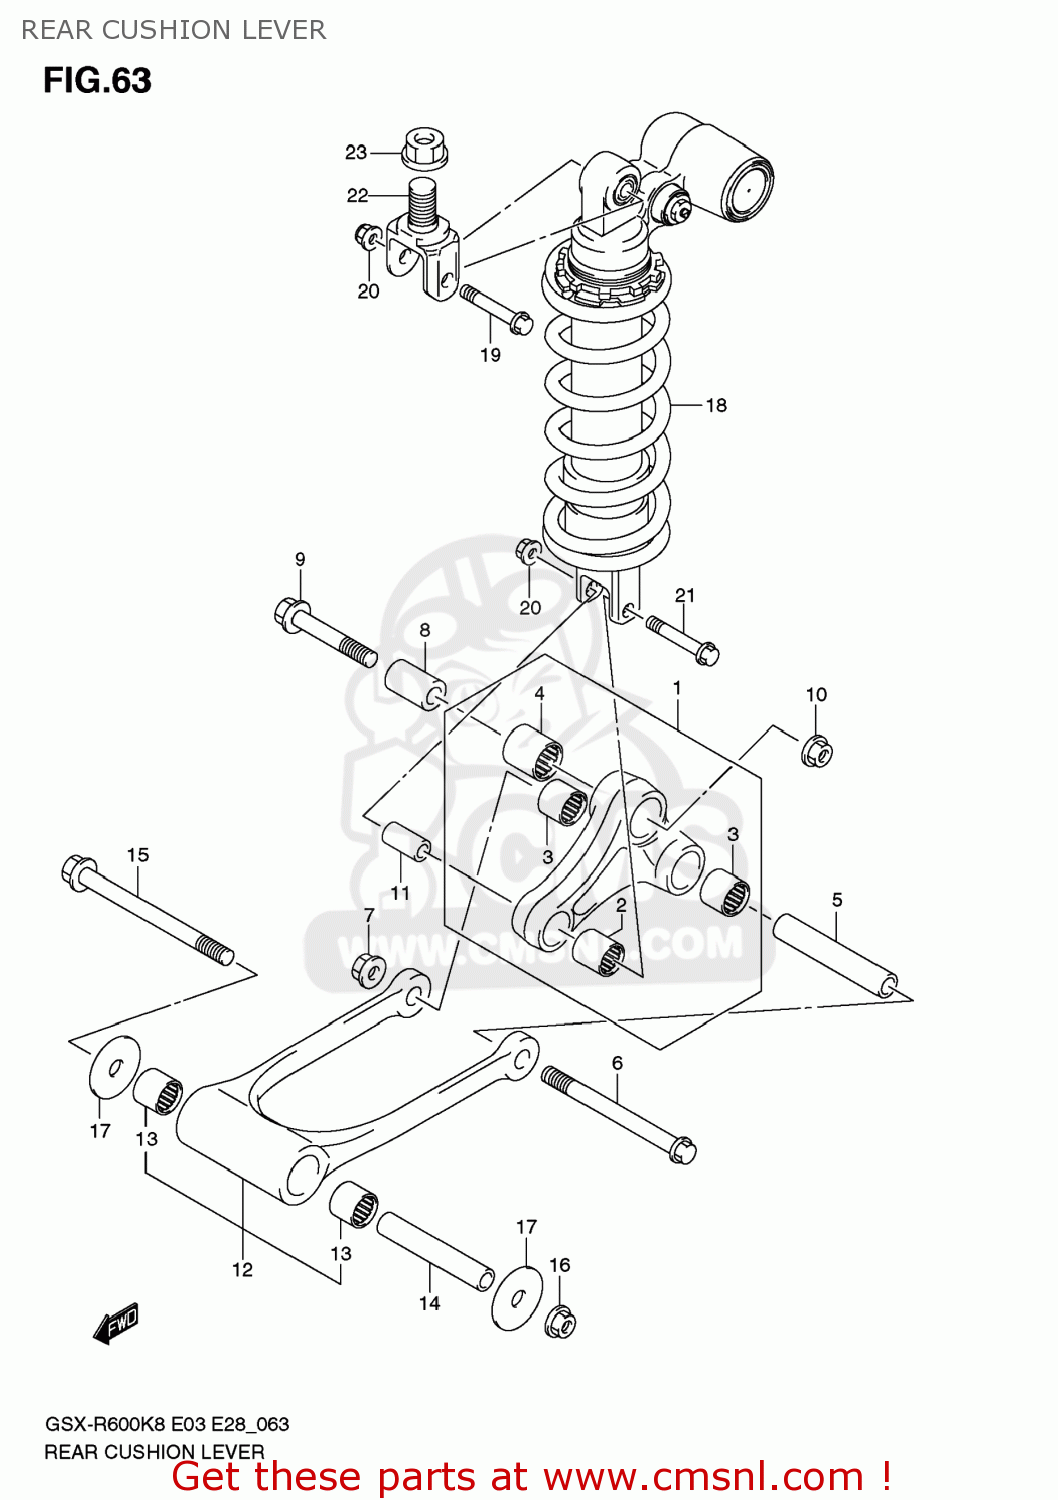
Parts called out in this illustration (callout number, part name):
1	LEVER SET,RR CUSHION
2	BEARING(17X24X26)
3	BEARING(17X24X25)
4	BEARING(20X27X32)
5	SPACER,RR CUSHION ROD
6	BOLT,RR CUSHION LEVER LWR
7	NUT
8	SPACER,RR CUSHION LEVER FR
9	BOLT,RR CUSHION LEVER FR
10	NUT
11	SPACER,RR CUSHION LEVER
12	ROD SET,RR CUSHION
13	BEARING(17X24X25)
14	SPACER,RR CUSHION LEVER CTR
15	BOLT,RR CUSHION ROD
16	NUT
17	WASHER(12X34X1)
18	ABSORBER ASSY,RR SHOCK(YELLOW)
19	BOLT(10X55)
20	NUT
21	BOLT(10X55)
22	BRACKET,RR SHOCK ABSORBER UPR
23	NUT
